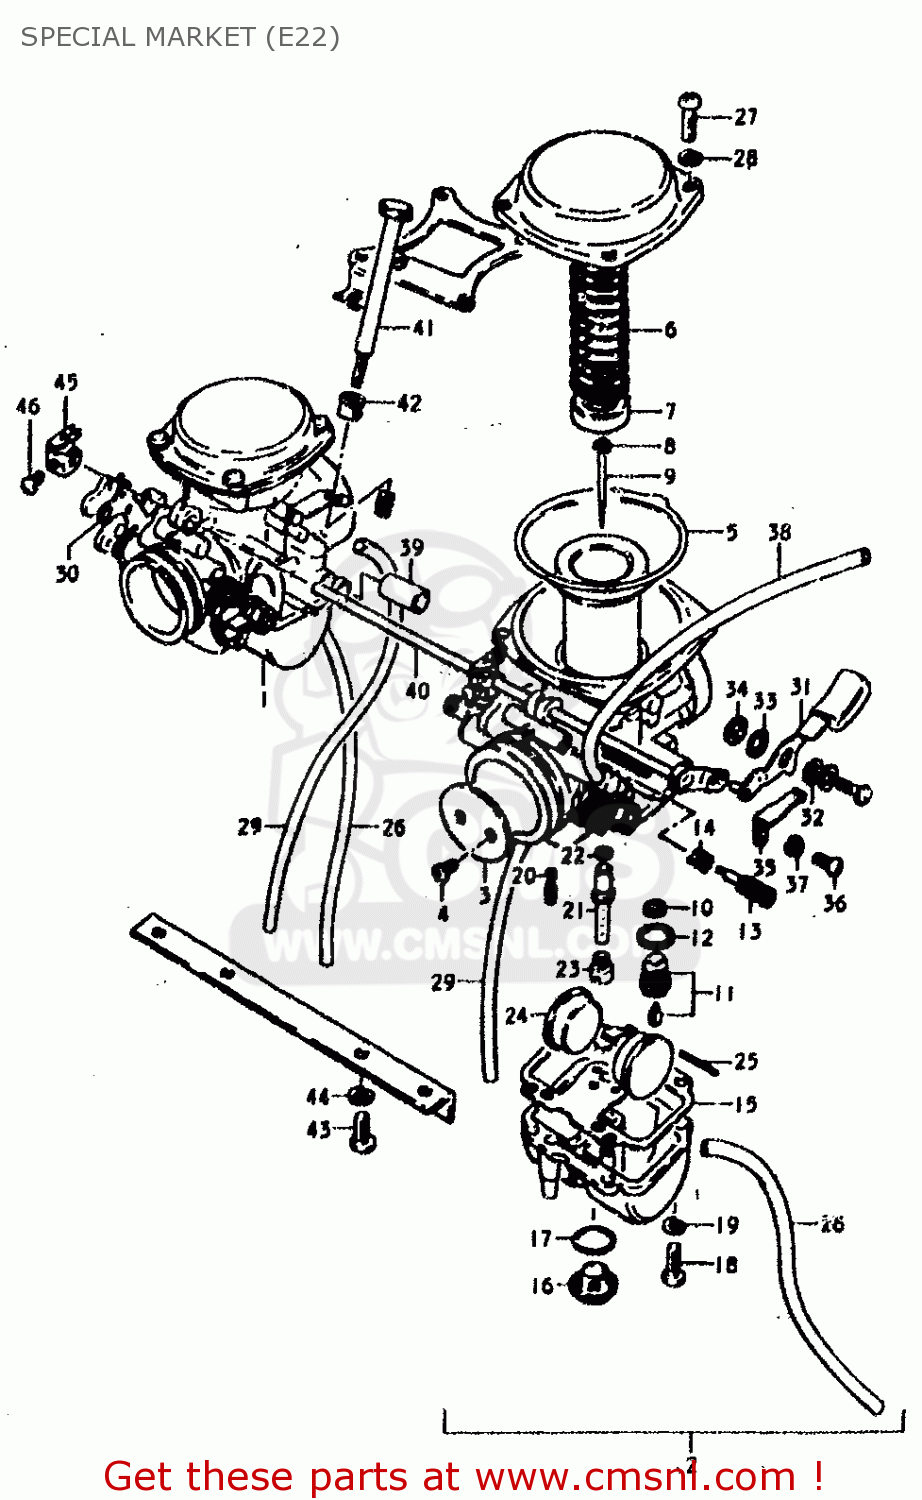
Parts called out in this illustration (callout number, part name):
1	CARBURETOR ASSY,RH
2	CARBURETOR ASSY,LH
3	VALVE,THROTTLE
4	SCREW
5	DIAPHRAGM ASSY
6	SPRING,DIAPHRAGM
7	CONNECTOR
8	CLIP
9	NEEDLE,JET
10	FILTER
11	VALVE ASSY,NEEDLE
12	GASKET,MAIN JET HOLDER (NAS)
13	SCREW,PILOT AIR
14	SPRING,THROTTLE SCREW
15	GASKET,FLOAT CHAMBER (NAS)
16	SCREW,GUIDE
17	O-RING
18	SCREW
19	LOCK WASHER
20	JET,PILOT
21	JET,NEEDLE
22	O-RING
23	JET,MAIN(112.5)
24	FLOAT
25	PIN,FLOAT
26	HOSE
27	SCREW
28	LOCK WASHER
29	HOSE
30	GASKET
31	LEVER
32	WASHER,STARTER LEVER
33	WASHER,STARTER LEVER
34	RING,STARTER LEVER
35	SPRING
36	SCREW
37	LOCK WASHER
38	HOSE
39	HOSE
40	SHAFT,STARTER
41	ADJUSTER
42	BUSH
43	SCREW 6X12
44	LOCK WASHER
45	LEVER, STARTER
46	SCREW
